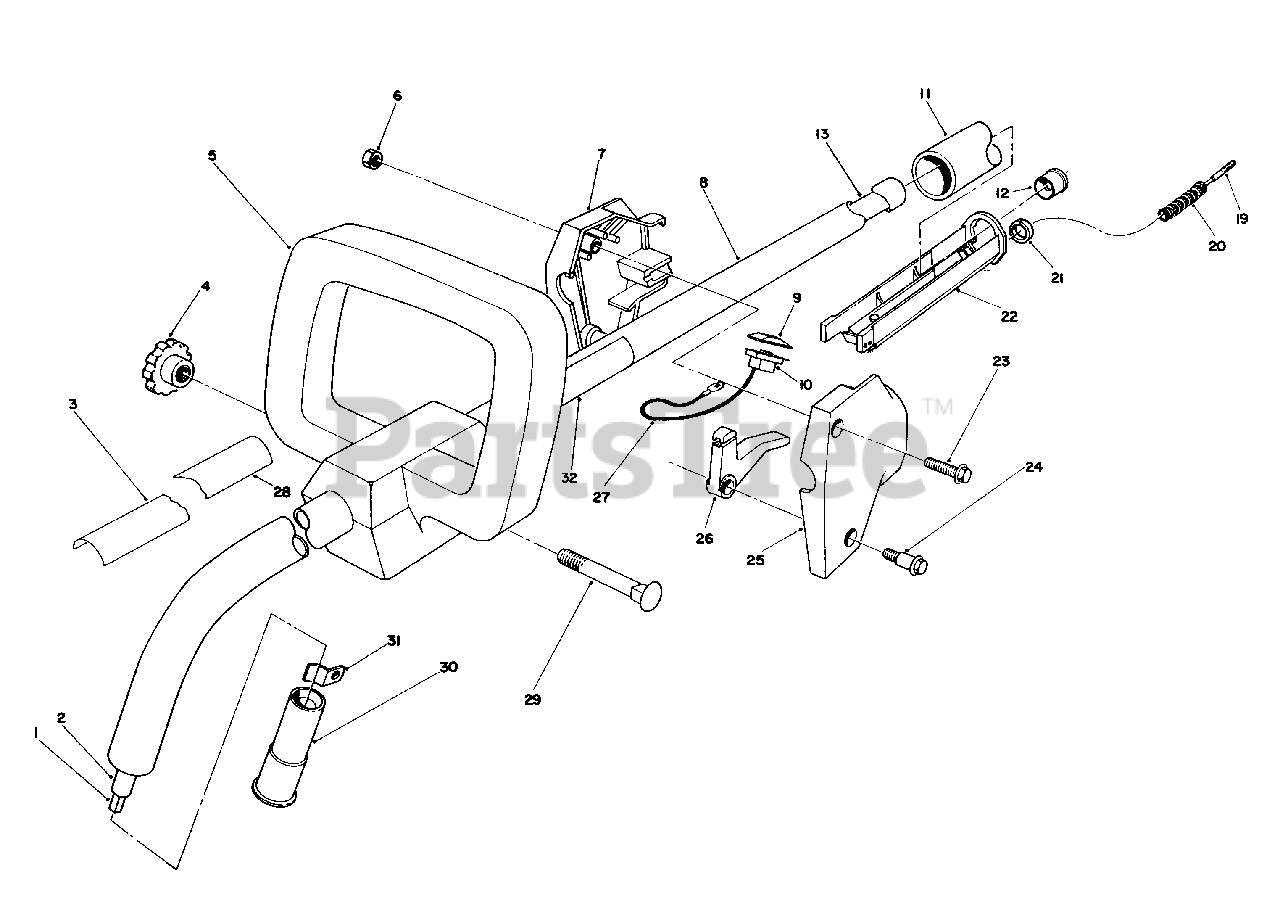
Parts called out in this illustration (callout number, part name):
1	Shaft-Wound Drive
2	Liner-Shaft
3	Decal-TC 2010
4	Knob-Handle Release
6	Nut-Lock
7	Housing-R.H.
8	Tube-Curved
9	Cap-Switch
12	Bushing-Pilot
19	Cable-Throttle
20	Cover-Cable
23	Screw-Hex. Washer Hd.
24	Screw-Shoulder
25	Housing-L.H.
26	Lever-Throttle
28	Decal-Warning
29	Bolt-Carriage
31	Retainer-Tube
32	Decal-Instructions
